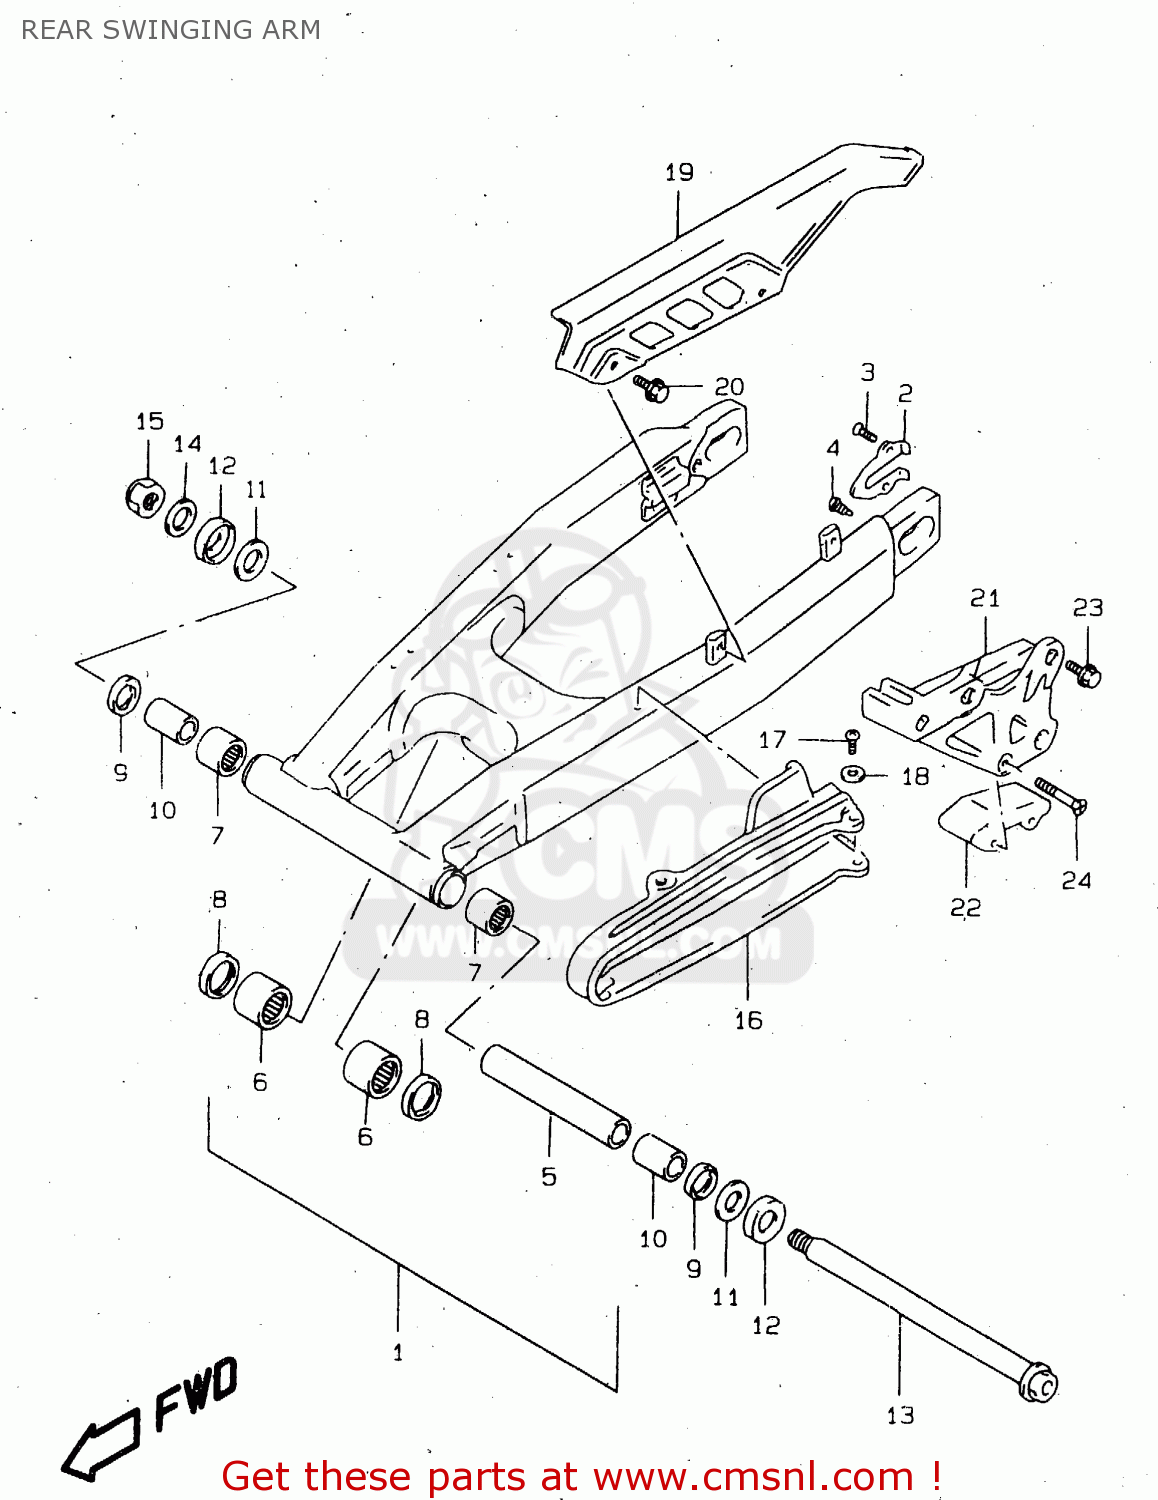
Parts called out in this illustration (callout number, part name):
1	SWING ARM ASSEMBLY,REAR
2	PLATE,RR SWING ARM AXLE
3	SCREW(5X8)
4	STOPPER,CHAIN ADJUSTER
5	SPACER,SWGARM PIVOT CTR
6	BEARING(20X27X23.5)
7	BEARING(22X29X30)
8	SEAL,OIL(20X27X5)
9	SEAL,OIL(22X29X4)
10	SPACER,SWGARM PIVOT BRG
11	WASHER
12	COVER,SWINGINGARM PIVOT
13	AXLE,RR
14	WASHER, FIXED DRIVE FACE
15	NUT
16	BUFFER,CHAIN TOUCH DEFENSE
17	SCREW 6X12
18	WASHER
19	CASE,CHAIN
20	BOLT(6X10)
21	GUIDE,CHAIN
22	DEFENSE,CHAIN GUIDE
23	BOLT
24	SCREW
